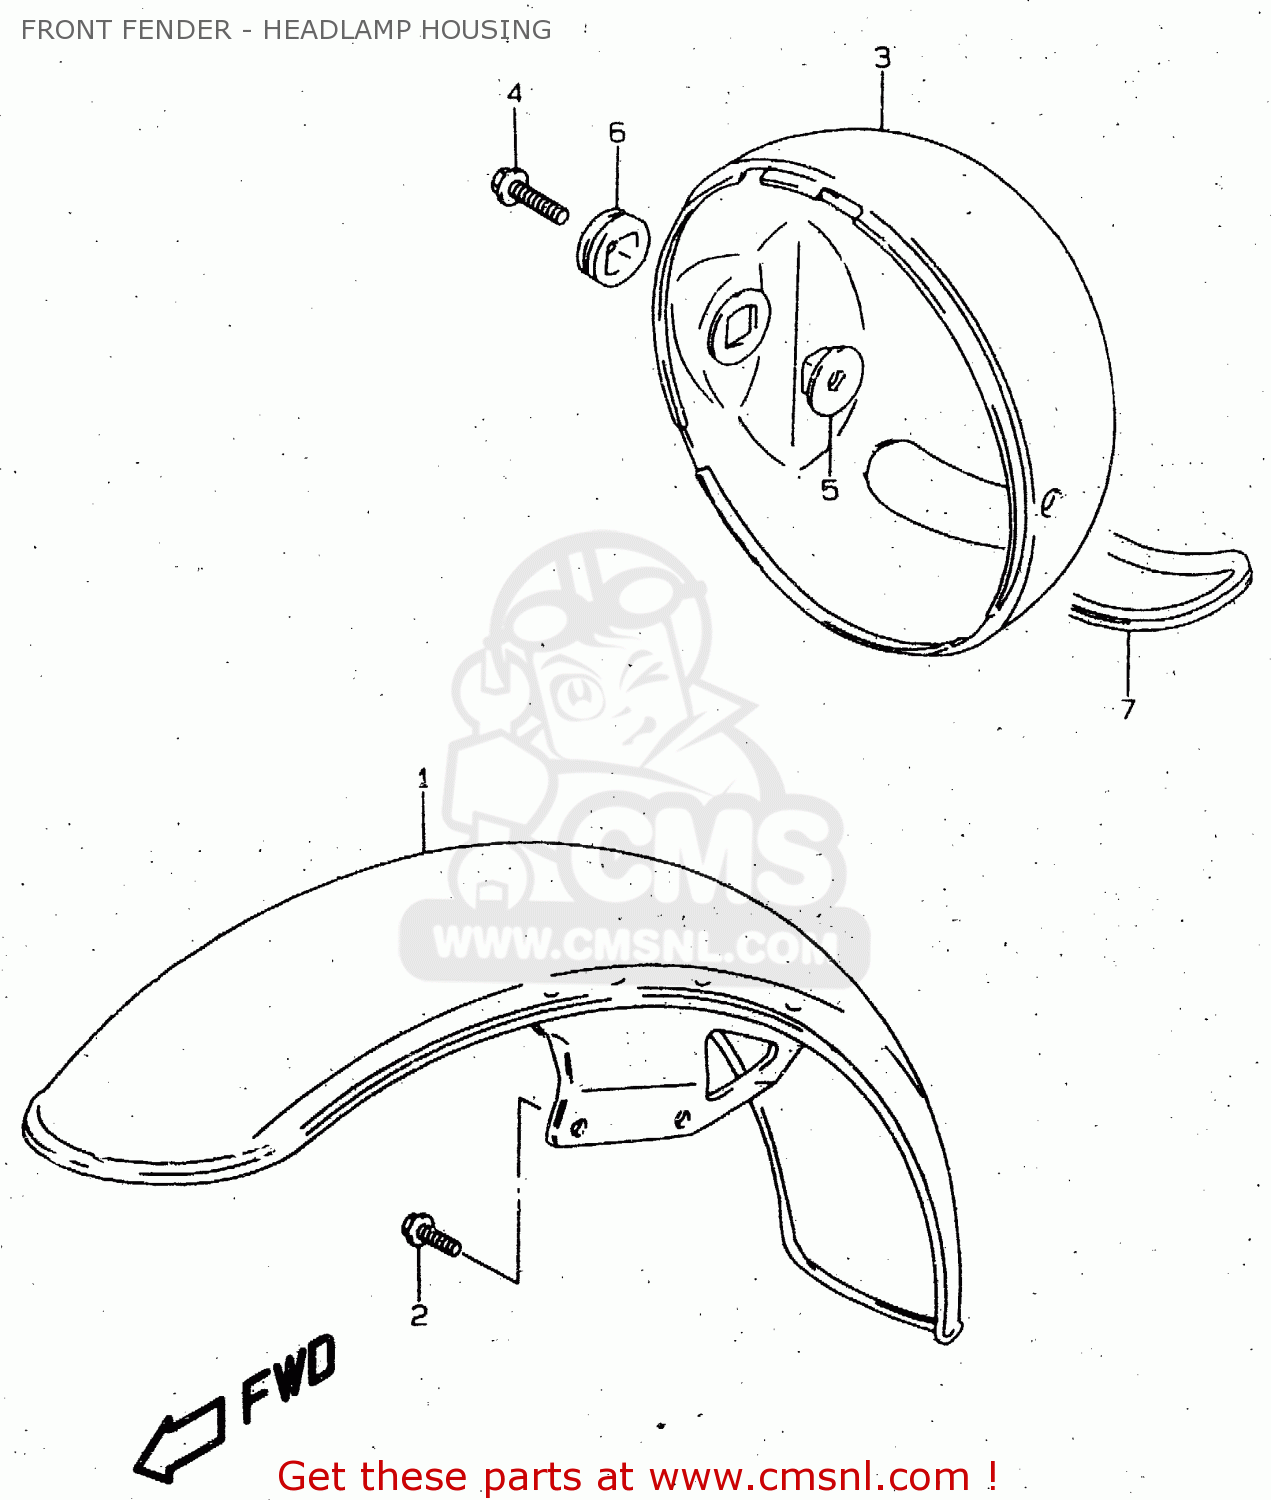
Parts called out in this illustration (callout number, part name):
1	FENDER,FR
2	BOLT, UPPER
3	HOUSING,HEADLAMP
4	BOLT
5	SPACER,HEADLAMP HOUSING
6	CUSHION,HEADLAMP HOUSING
7	MOLDING WINDSCREEN
